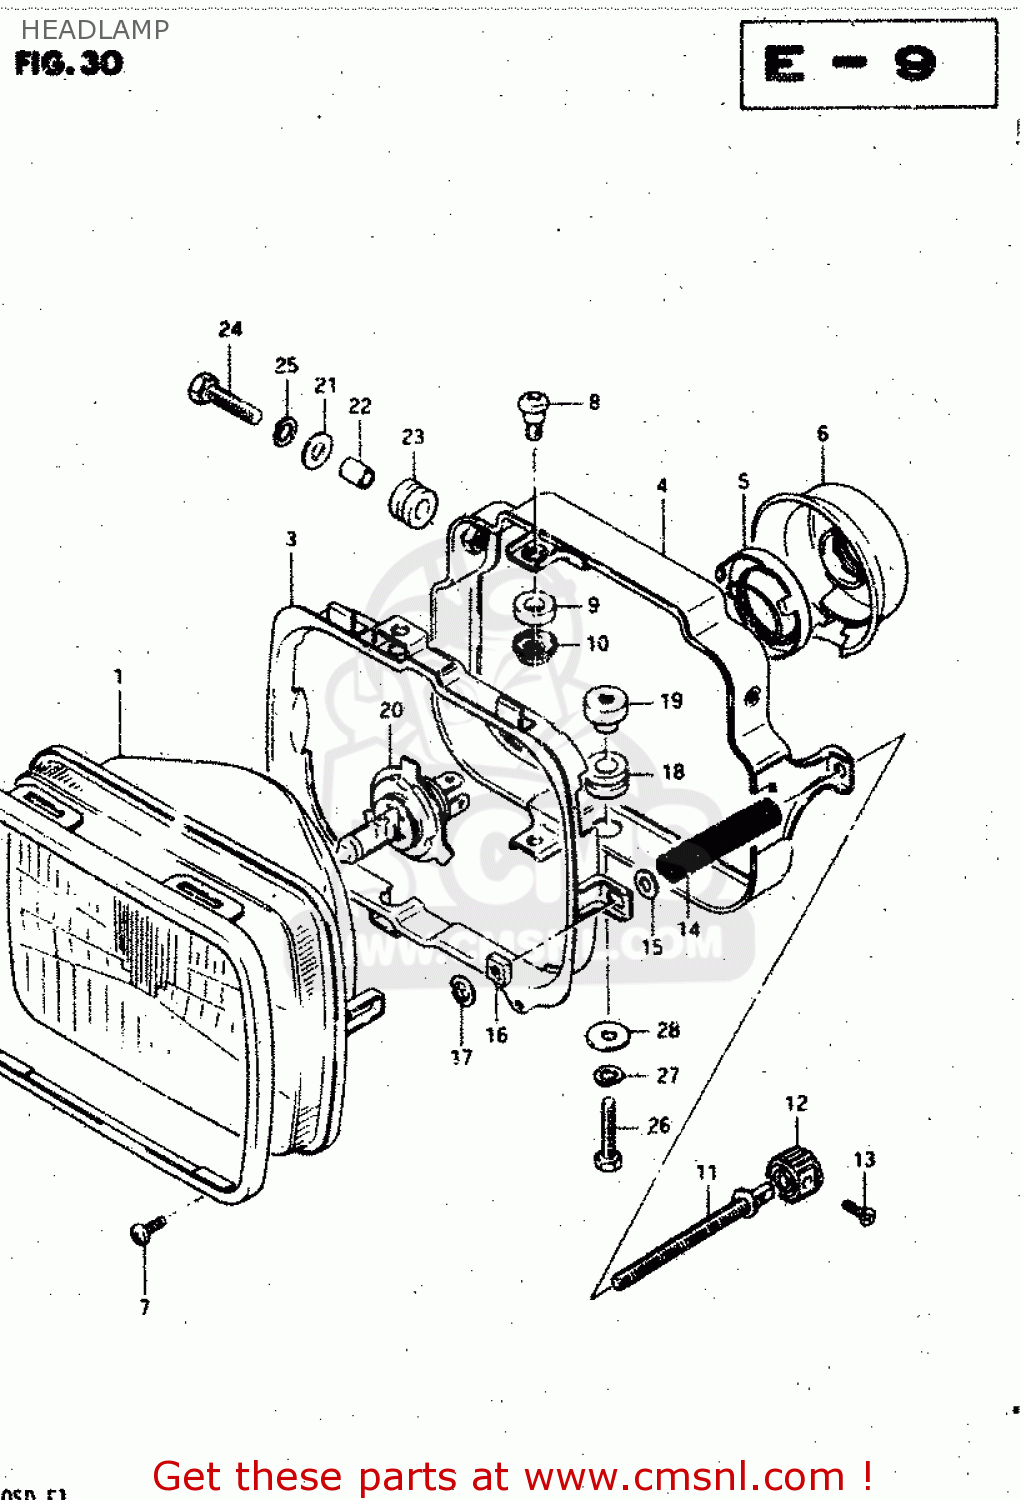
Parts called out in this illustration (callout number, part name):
1	LAMP UNIT
2	RETAINER
3	RING,MOUNTING
4	HOUSING
5	HOLDER
6	COVER,HEADLAMP SOCKET
7	SCREW
8	SCREW
9	SPACER
10	NUT,ADJUSTING
11	SCREW,ADJUSTING
12	KNOB,ADJUSTER
13	SCREW
14	SPRING
15	WASHER
16	NUT
17	NUT,HEADLAMP ADJUSTER
18	CUSHION
19	NUT
20	BULB(12V60/55W,H4)
21	WASHER
22	SPACER (6.1X8X9.5)
23	CUSHION
24	BOLT
25	LOCK WASHER
26	SCREW(6X20)
27	LOCK WASHER
28	WASHER
